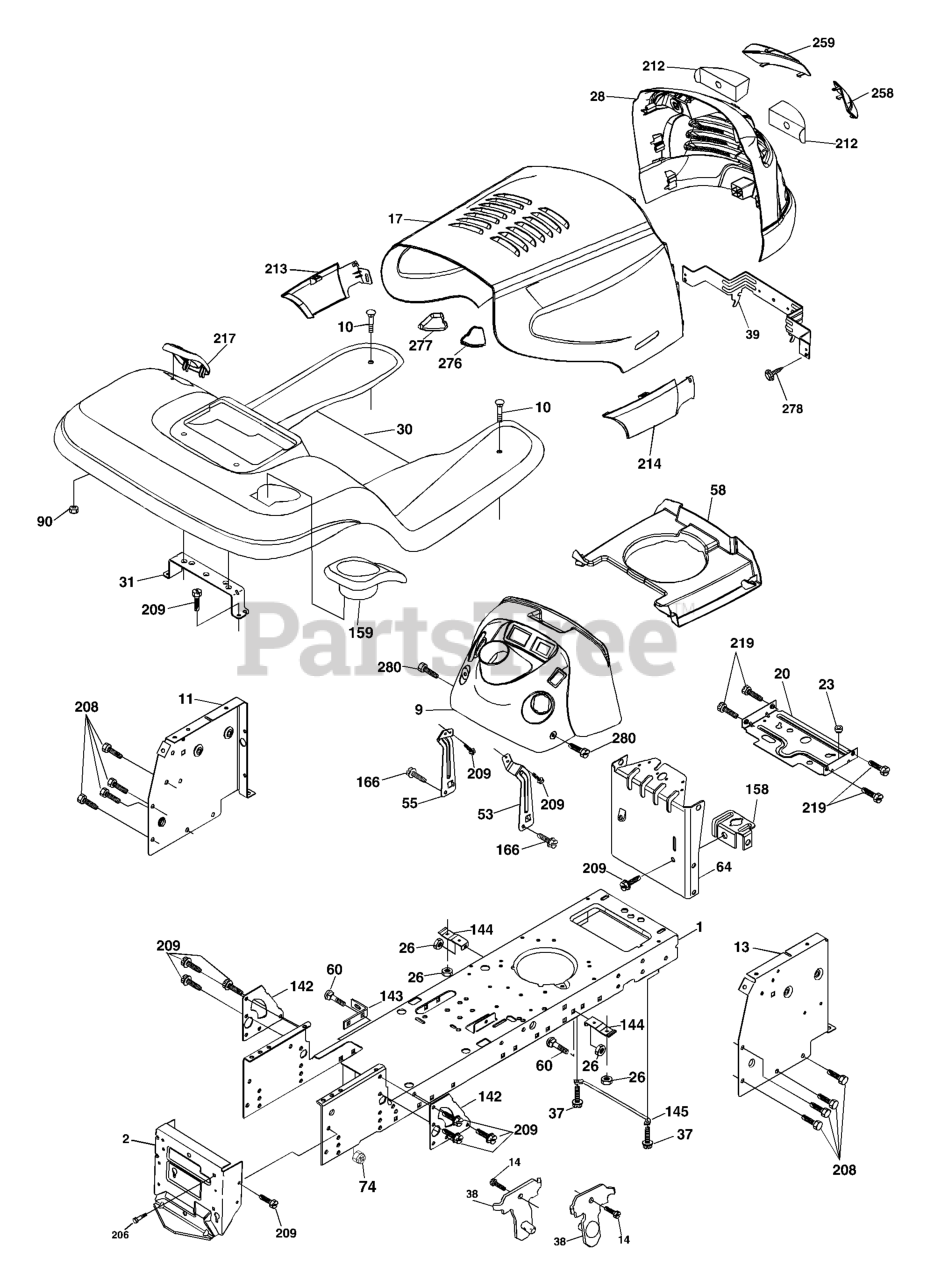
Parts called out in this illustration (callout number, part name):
1	CHASSIS STAMPING
2	DRAWBAR, 12GA
9	DASH
10	BOLT D
11	PANEL.DASH.LH.LTX
13	PANEL ASM, DASH RH
14	SCREW LT
17	HOOD
20	PLATE MTG.BATTERY/FUEL TANK
23	BUSHING.SNAP.NYL.BLK.
26	NUT
28	GRILL
30	FENDER
31	BRACKET.SUPPORT.FENDER
37	Screw Thdrol 5/16-18 x 1/2
38	BRACKET.ASM.PIVOT.MOWER.REAR
39	BRACKET PIVOT LASER
53	BRACKET DASH RH
55	BRACKET DASH LH
60	Bolt RDHD SQNK 3/8-16 x 3/4
64	DASH LOWER
90	NUT.PUSH.3/16
142	PLATE REINFORCEMENT
143	BRACKET, SWAYBAR CHASSIS
144	BRKT, FOOT REST
145	ROD PIVOT CHASSIS/HOOD
158	BRACKET PARKING BRAKE
159	GREY CUP HOLDER
206	SHOULDER BOLT 5/16-18TT
208	SCREW 3/8-16X1/2
209	SCREW, 3/8-16X3/4
212	INSERT LENS
213	SKIRT SIDE LH
214	SKIRT SIDE RH
217	CONSOLE FUEL WINDOW
219	SCREW, 3/8-16X3/4
258	LENS ELITE CLEAR RH
259	LENS ELITE CLEAR LH
276	BUMPER HOOD RH
277	BUMPER HOOD LH
278	SCREW
280	SCREW THDROL 3/8-16 X 1-1/2
